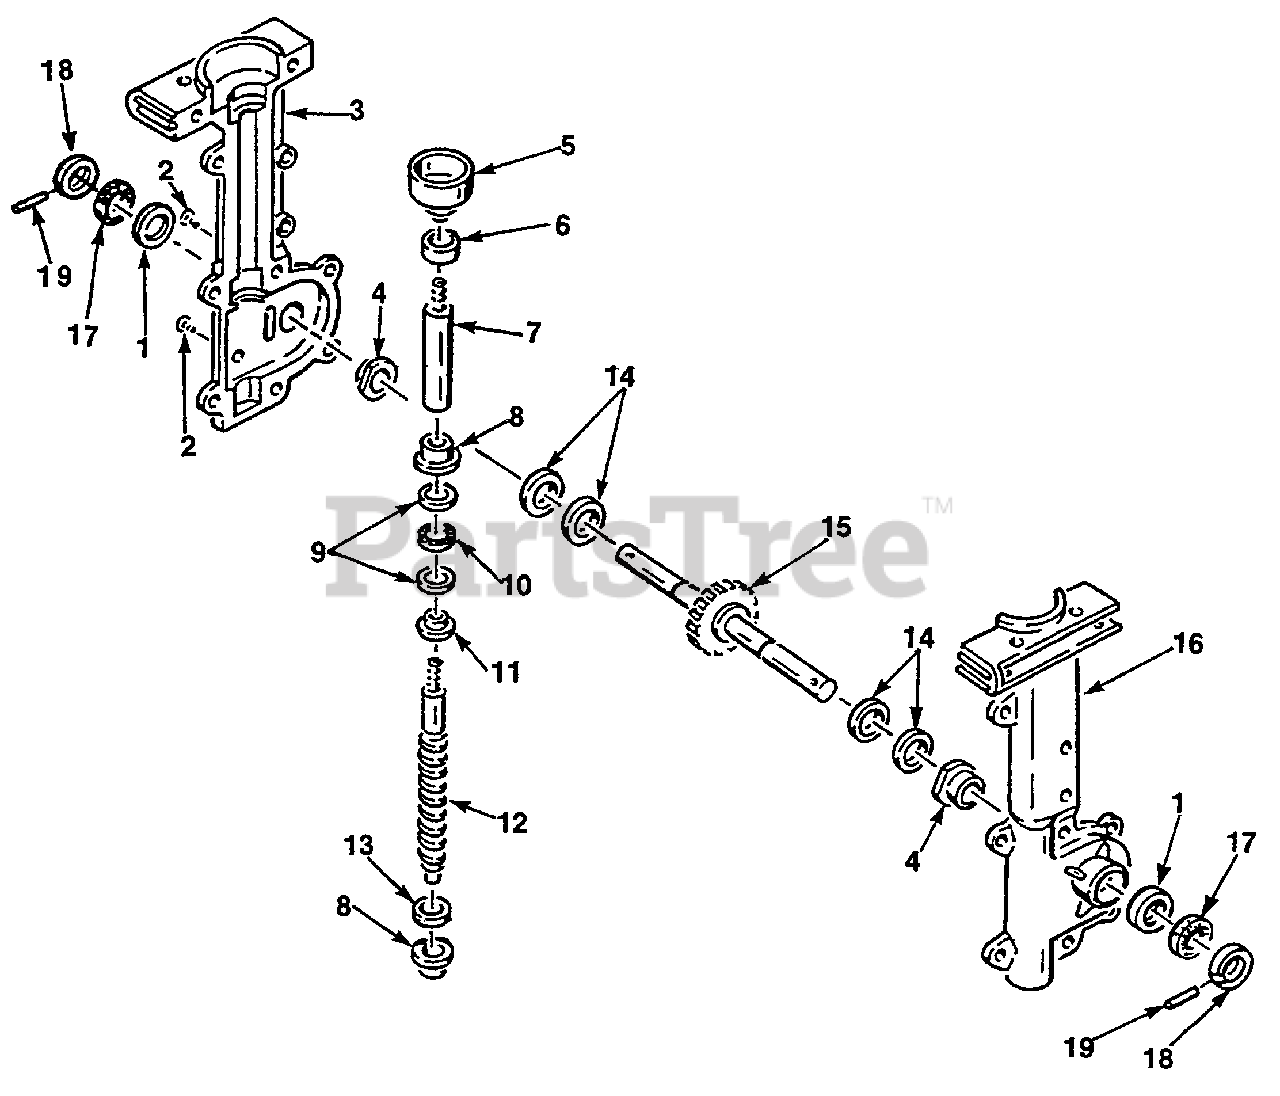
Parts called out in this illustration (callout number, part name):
1	SEAL- Lip 3/4"
2	SCREW- Slotted hex hd. 1/4-20 x 1/2"
3	HOUSING- Reduction, R.H.
4	BUSHING- Bronze, 3/4" I.D.
5	DRUM & HUB- Clutch
6	BEARING- Roller
7	SHAFT- Connecting
8	BUSHING- Bronze, 7/16"
9	WASHER- Thrust Hardened
10	BEARING- Needle. Thrust
11	WASHER- Adaptor
12	SHAFT- Worm (16P)
13	WASHER, Thrust 3/4 x 7/16"
14	WASHER- Thrust 16 x 3/4 x 1 1/2"
15	SHAFT- Tine, w/Worm Wheel
16	HOUSING- Reduction, L.H.
17	WASHER- Felt Seal 1/8 x 3/4 x 1 1/4"
18	DIRT CAP- Silver Metal
19	SCREW- Set, #10-32 x 1/4" Metal Dirt Cap
